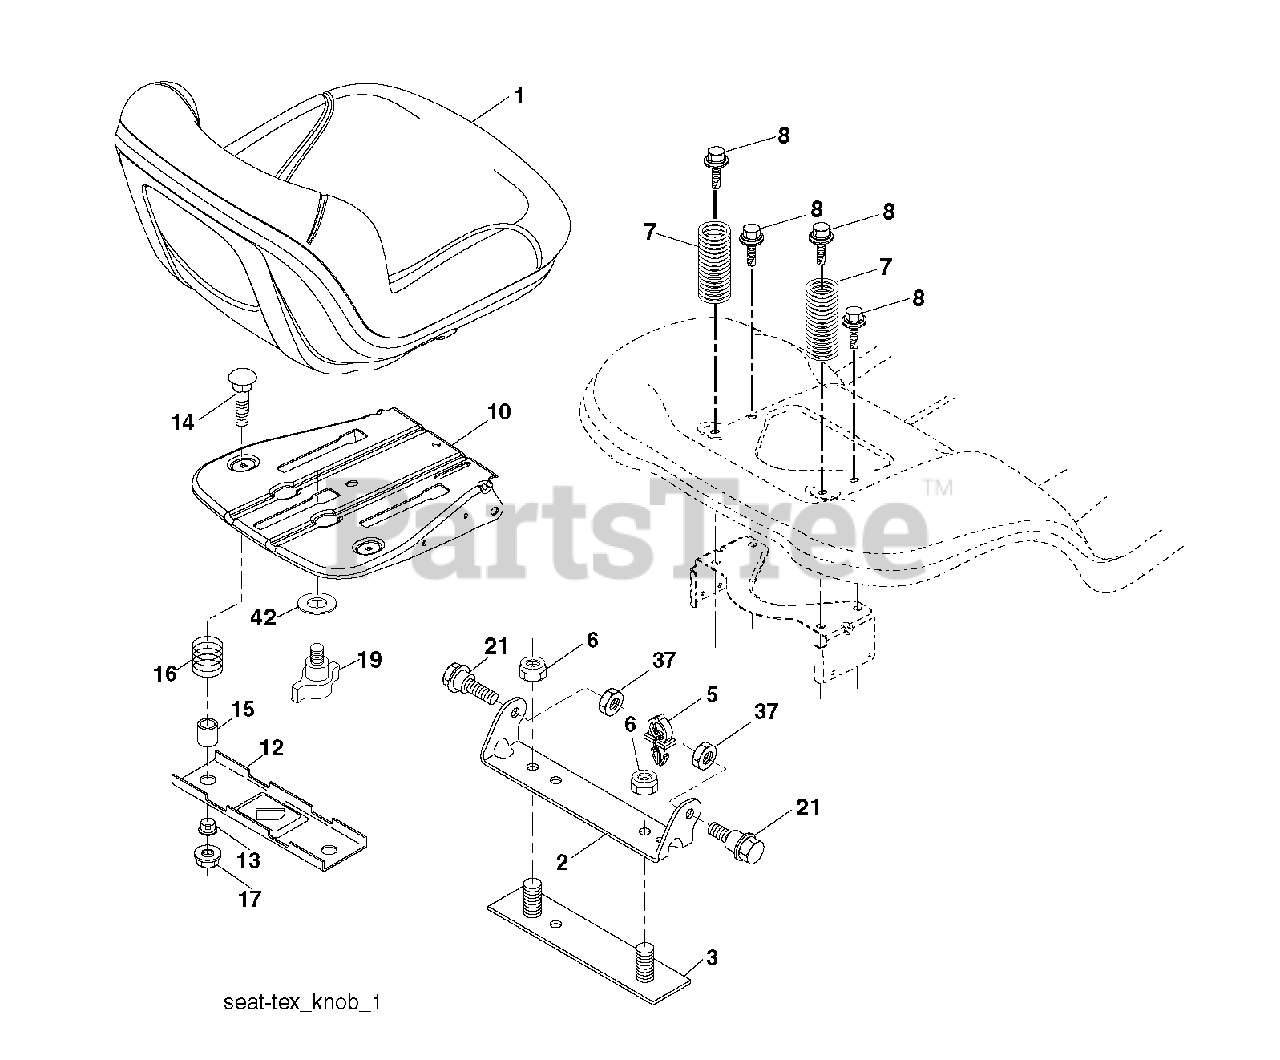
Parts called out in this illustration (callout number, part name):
1	SEAT.TG130.BLACK.NO/LOGO.
2	BRKT.PIVOT.FENDER
5	PUSH CLIP
6	NUT
7	SPRING COMPRESSION
8	BOLT, 5/16-18 X 1 3/4
10	PAN.ASM.SEAT.SHORT
12	BRKT.MNT.OPC.SW.SEAT.
14	BOLT.ROUND.HEAD.SQUARE.NECK
15	SPACER SPLIT 28X.96
16	SPRING COMPRESSED
17	NUT T
19	KNOB.SEAT.ADJ.
21	BOLT.SHOULDER.5/16-18
37	NUT.71038.31-18.HEX.NYLOCK
42	WASHER.CUP.SEAT.
